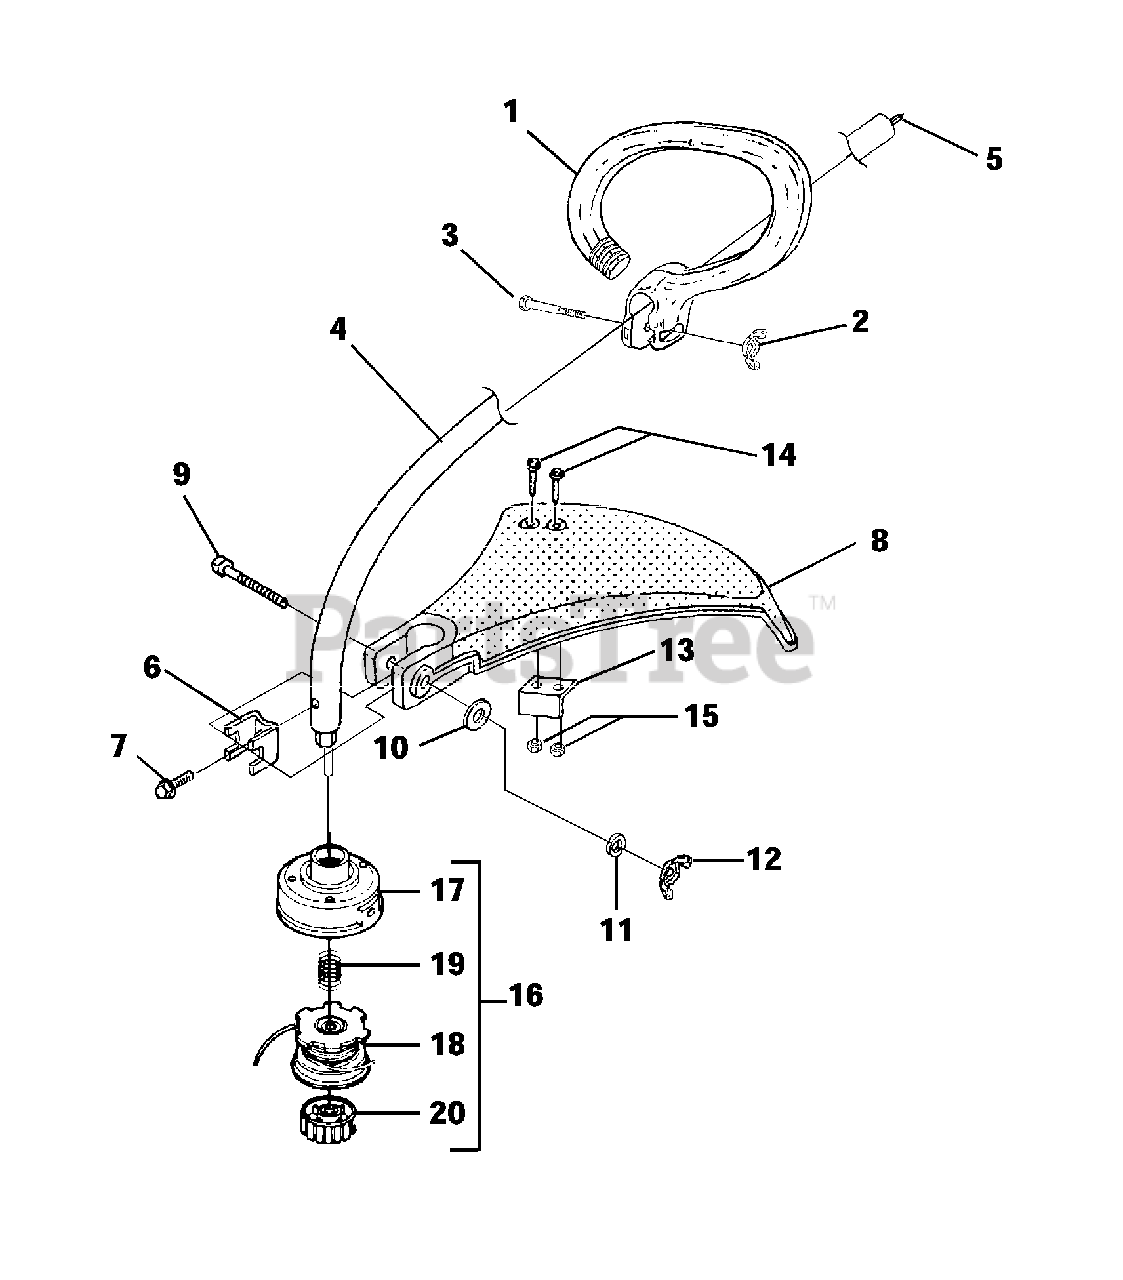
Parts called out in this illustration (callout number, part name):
1	HANDLE ASSY.-Front
2	NUT-Wing, Washer Faced (1/4-20)
3	SCREW-Cap Hex Hd.
4	DRIVESHAFT HOUSING ASSY.
5	SHAFT-Flexible
6	CLAMP
7	SCREW-Sems Hex Hd. (#10-24 X 3/8")
8	DEFLECTOR & BLADE KIT (55 Deg.)
9	SCREW-Cap Hex Hd. (10-24 X 2")
10	WASHER-Flat (1/4")
11	WASHER-Lock (1/4")
12	NUT-Wing, Washer Faced (1/4-20)
13	BLADE-Cut-Off
14	SCREW-Mech. Hex Hd. (10-24 X 7/8")
15	NUT-Hex (10-24)
16	STRINGHEAD-Complete (.080")
17	HOUSING & EYELET (Dual Line)
18	SPOOL & STRING (.080")
19	SPRING-Compression
20	RETAINER-Spool (R.H. Thread, Black)
